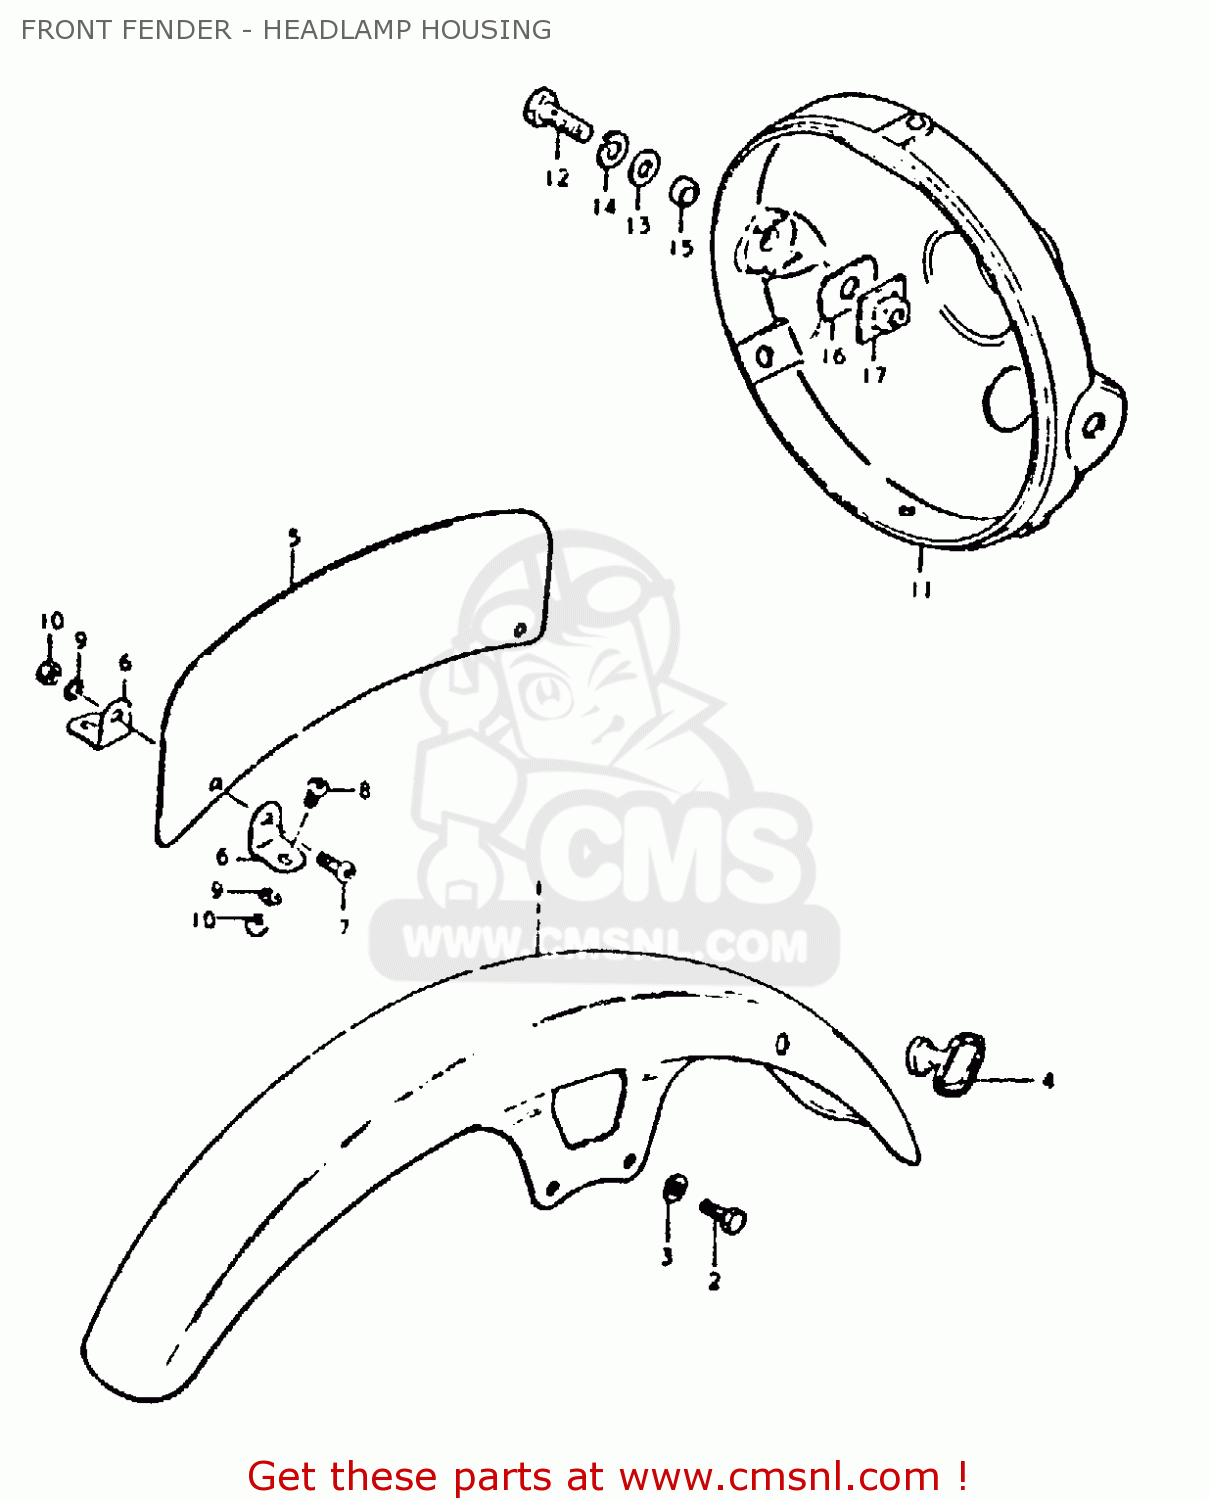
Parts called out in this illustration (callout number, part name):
1	FENDER,FR
2	BOLT
3	LOCK WASHER
4	GUIDE,CABLE
11	HOUSING,HEADLAMP(BLACK)
12	BOLT
13	WASHER
14	LOCK WASHER
15	SPACER (8.8X12X7)
16	CUSHION
17	PLATE,HEADLAMP HOUSING
